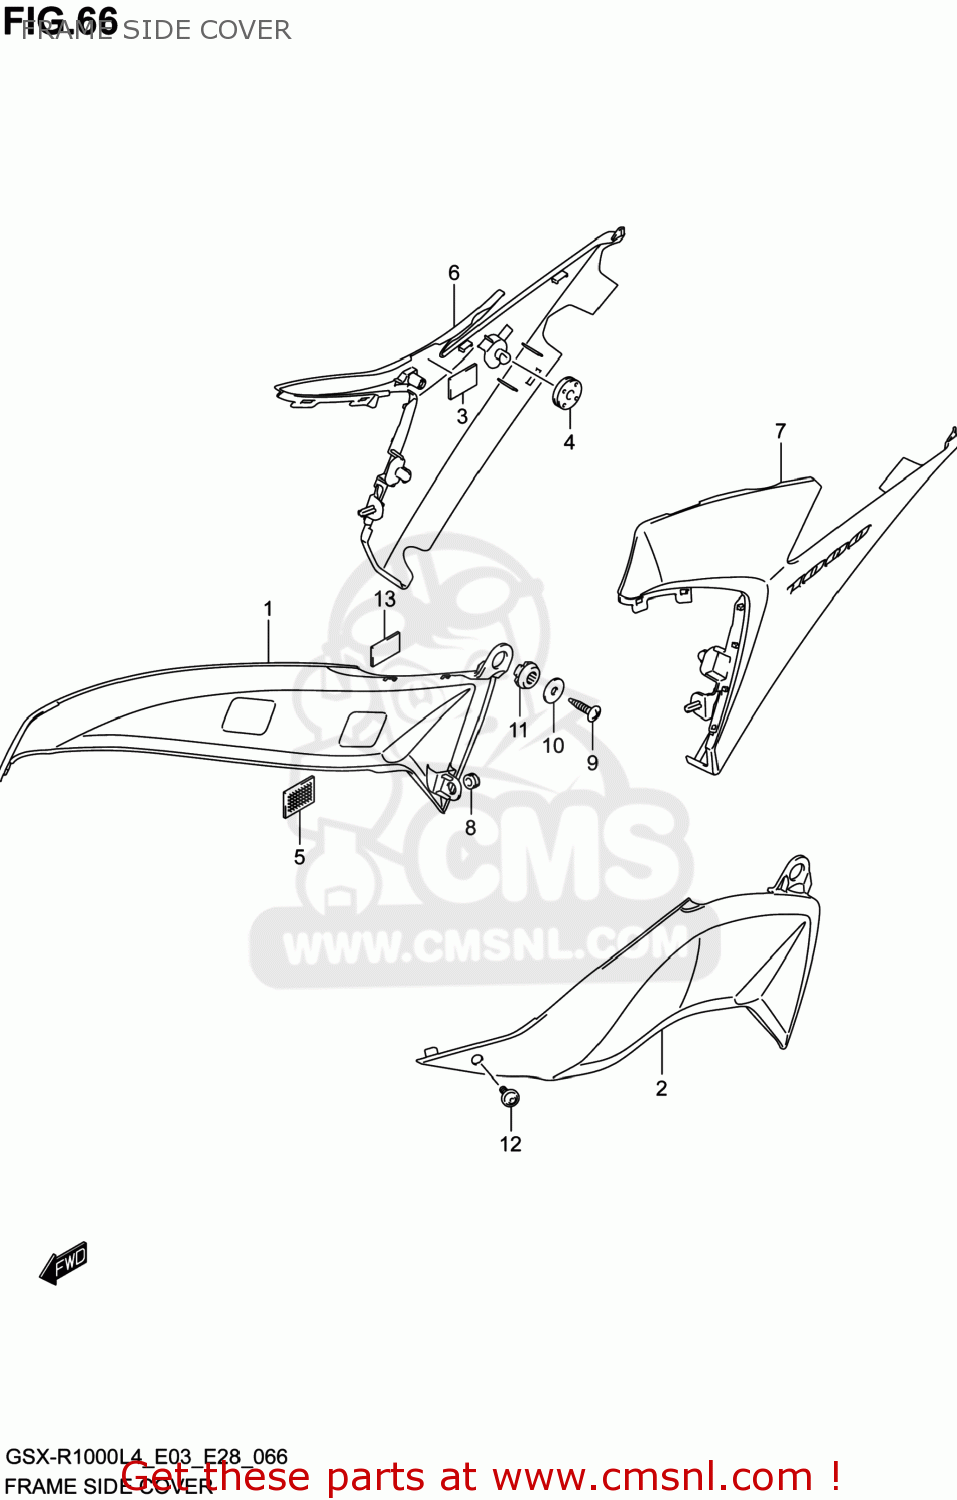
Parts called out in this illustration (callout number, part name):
1	COVER,FRAME SIDE FR,R
2	COVER,FRAME SIDE FR,L
3	CUSHION,FUEL TANK ATTACHMENT
4	CUSHION
5	FASTENER
6	COVER,FRAME SIDE,R
7	COVER,FRAME SIDE,L
8	CUSHION
9	SCREW
10	WASHER(5.5X20X1.2)
11	CUSHION
12	SCREW(5X13)
13	CUSHION(40X20X5)
